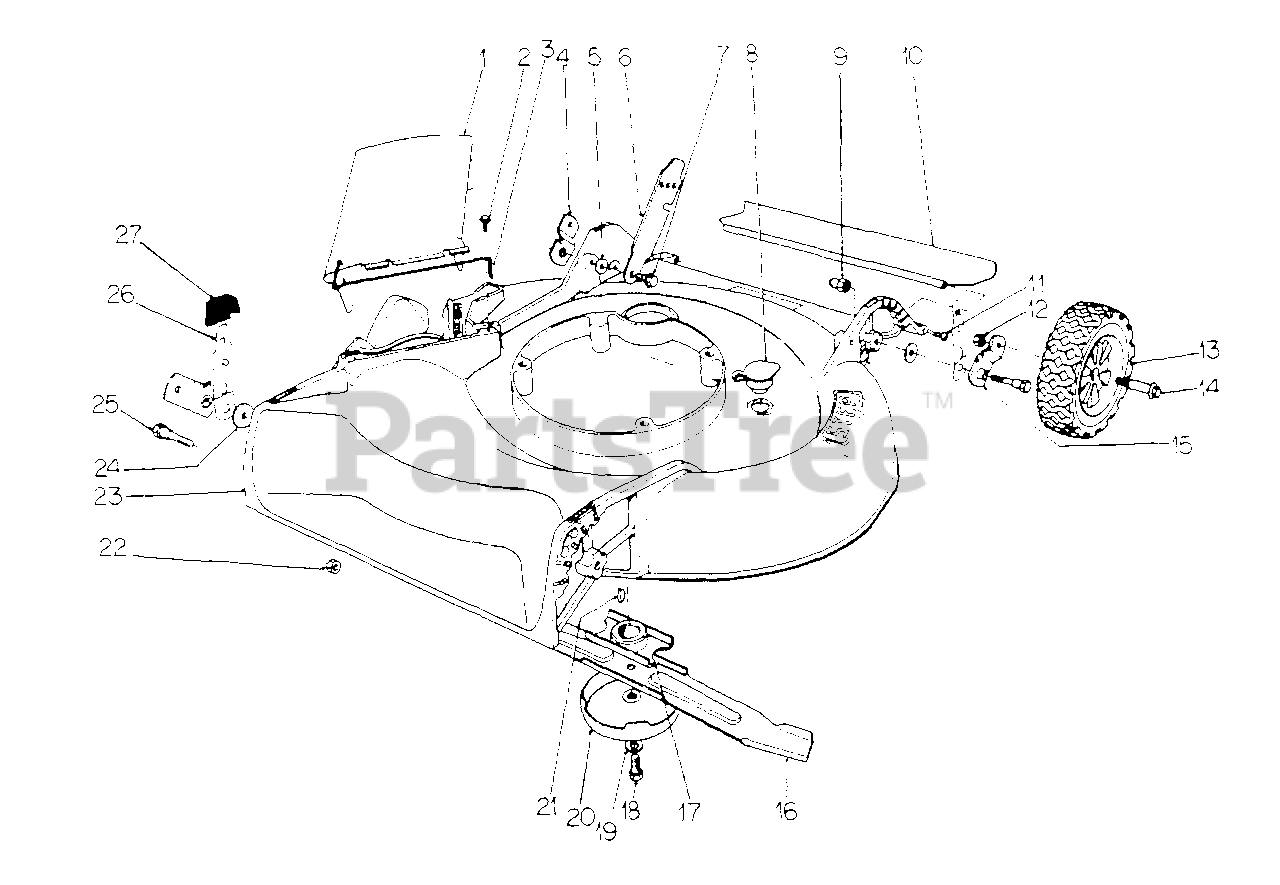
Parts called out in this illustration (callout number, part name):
3	SPRING, HINGE
4	ARM, PIVOT - LEFT FRONT, RIGHT REAR
5	SPACER, HANDLE LATCH
6	LATCH, HANDLE
7	BOLT, SHOULDER
7	SCREW, SHOULDER
8	PLUG, WASH-OUT
10	SHIELD, REAR
13	WHEEL W/TIRE, FRONT
13	WHEEL W/TIRE, REAR
14	BOLT, WHEEL
15	ARM, PIVOT -RIGHT FRONT, LEFT REAR
16	BLADE, 19 IN. CUTTING
17	RETAINER, BLADE
18	BOLT, BLADE
19	WASHER, 7/16 PLN HV LOCK
20	CUP, ANTI-SCALP
21	KEY, 3/16 X 5/8 WOODRUFF 61
22	NUT, 5/16 CAD P/T LOCK TYPE 1
23	HOUSING, MOWER
25	BOLT, PIVOT
26	ARM, SPRING
